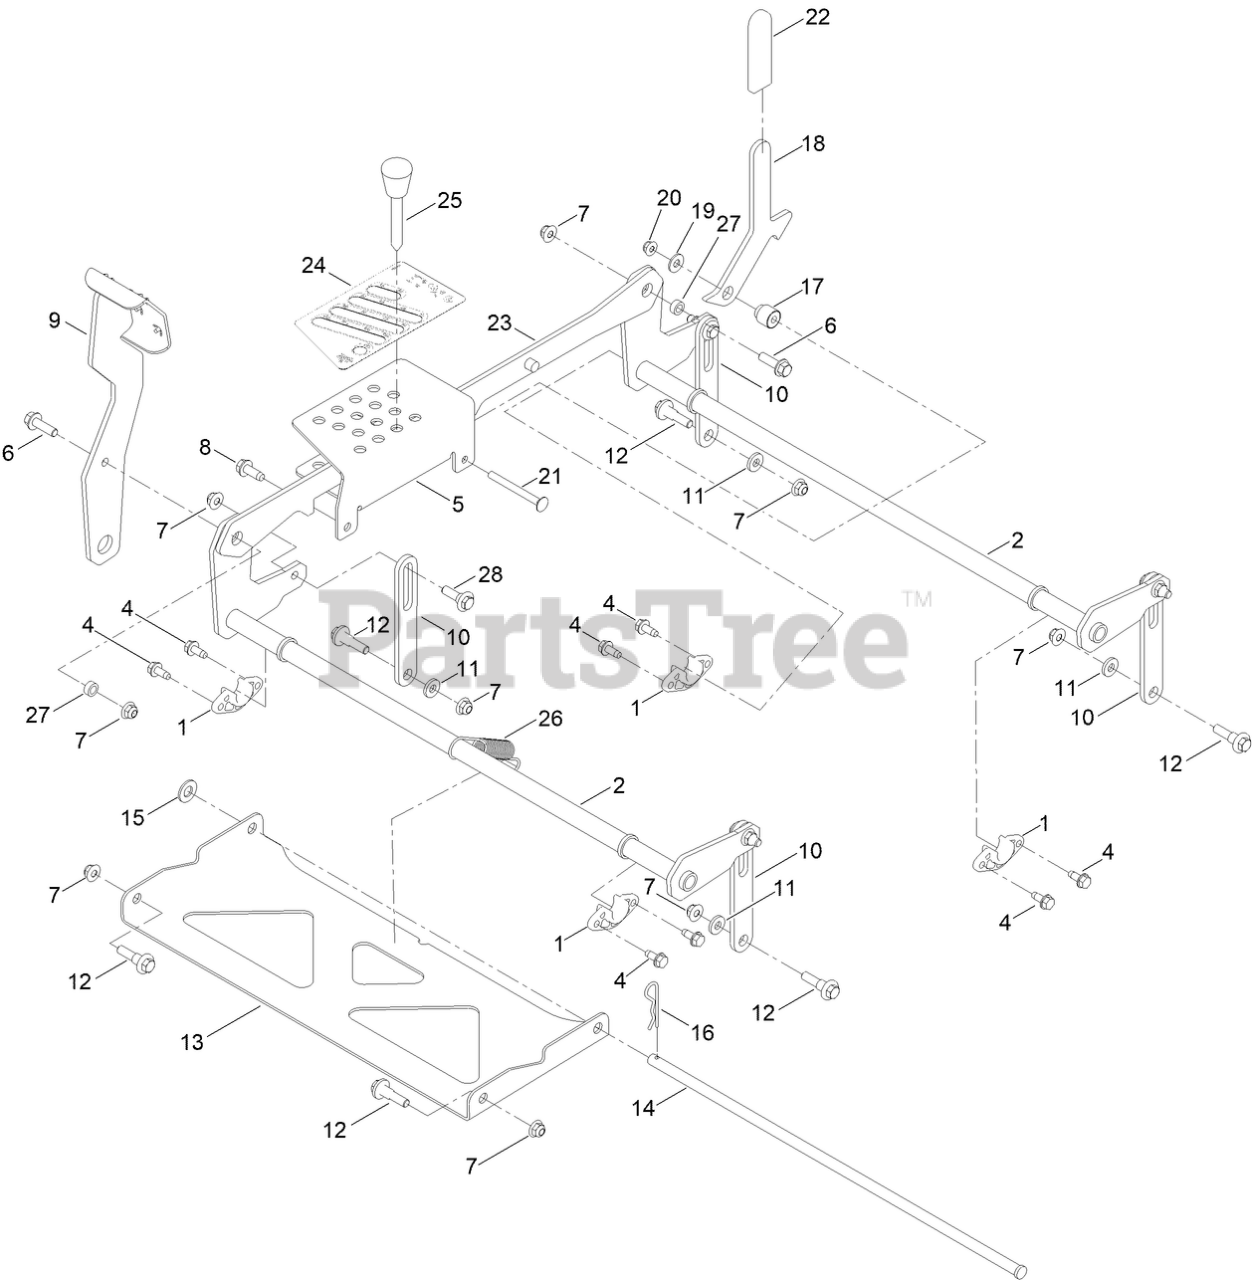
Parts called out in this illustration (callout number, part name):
1	BEARING-FLANGE
2	PIVOT ASM-DECKLIFT [RED]
4	SCREW-HWHTF
5	BRACKET-HOC
6	SCREW-HHF
7	NUT-HF, NI
8	SCREW-HWH
9	PEDAL ASM [RED]
10	LINK-HOC
11	SPACER-HUB, BLOWER
12	BOLT-SHOULDER
13	PAN-DECK PIVOT
14	PIN-DECK
15	WASHER-FLAT
16	PIN-HAIR
17	SPACER-STEPPED
18	PLATE-TRANSPORT LOCK
19	WASHER-PLAIN
20	NUT-HF
21	SCREW-CARR
22	GRIP-HANDLE
23	LINK ASM-HOC [RED]
24	DECAL-HOC
25	HOC PIN ASM
26	SPRING-EXTENSION
27	SPACER
28	SCREW-SHOULDER, HWH
